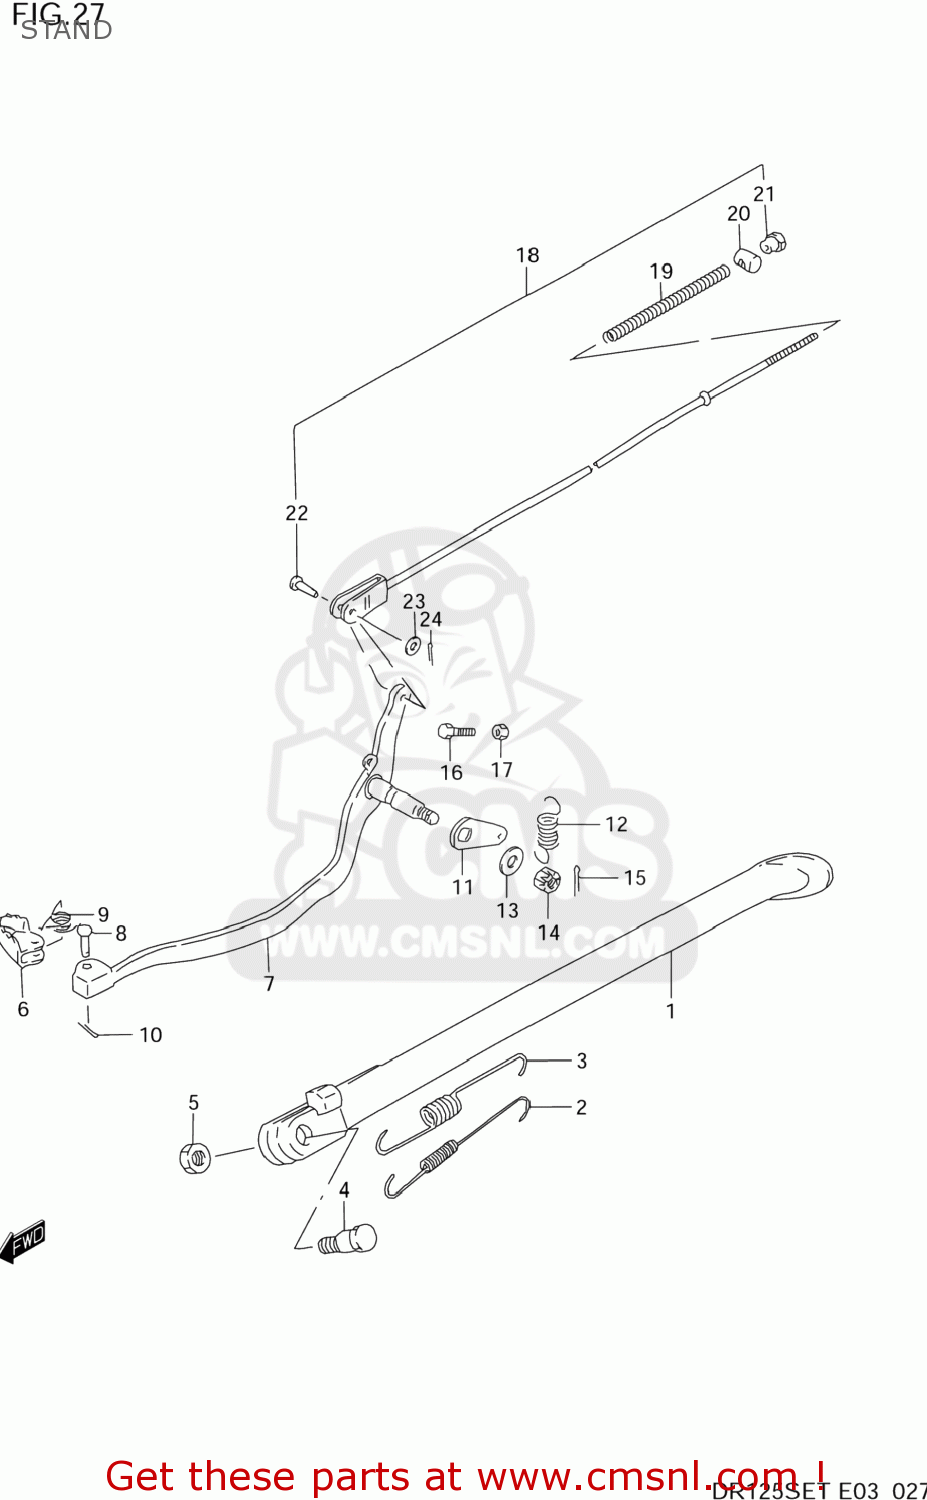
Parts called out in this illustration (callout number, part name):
1	STAND COMP,PROP
2	SPRING
3	SPRING
4	BOLT L:30
5	NUT
6	PEDAL,BRAKE
7	ARM,BRAKE PEDAL
8	PIN
9	SPRING
10	PIN
11	ARM,BRAKE RETURN SPRING
12	SPRING
13	WASHER
14	NUT
15	PIN 20X20
16	BOLT(6X23)
17	NUT 6MM
18	ROD ASSY,RR BRAKE
19	SPRING
20	PIN
21	NUT (6MM)
22	PIN(L:13.5)
23	WASHER
24	PIN 20X20
